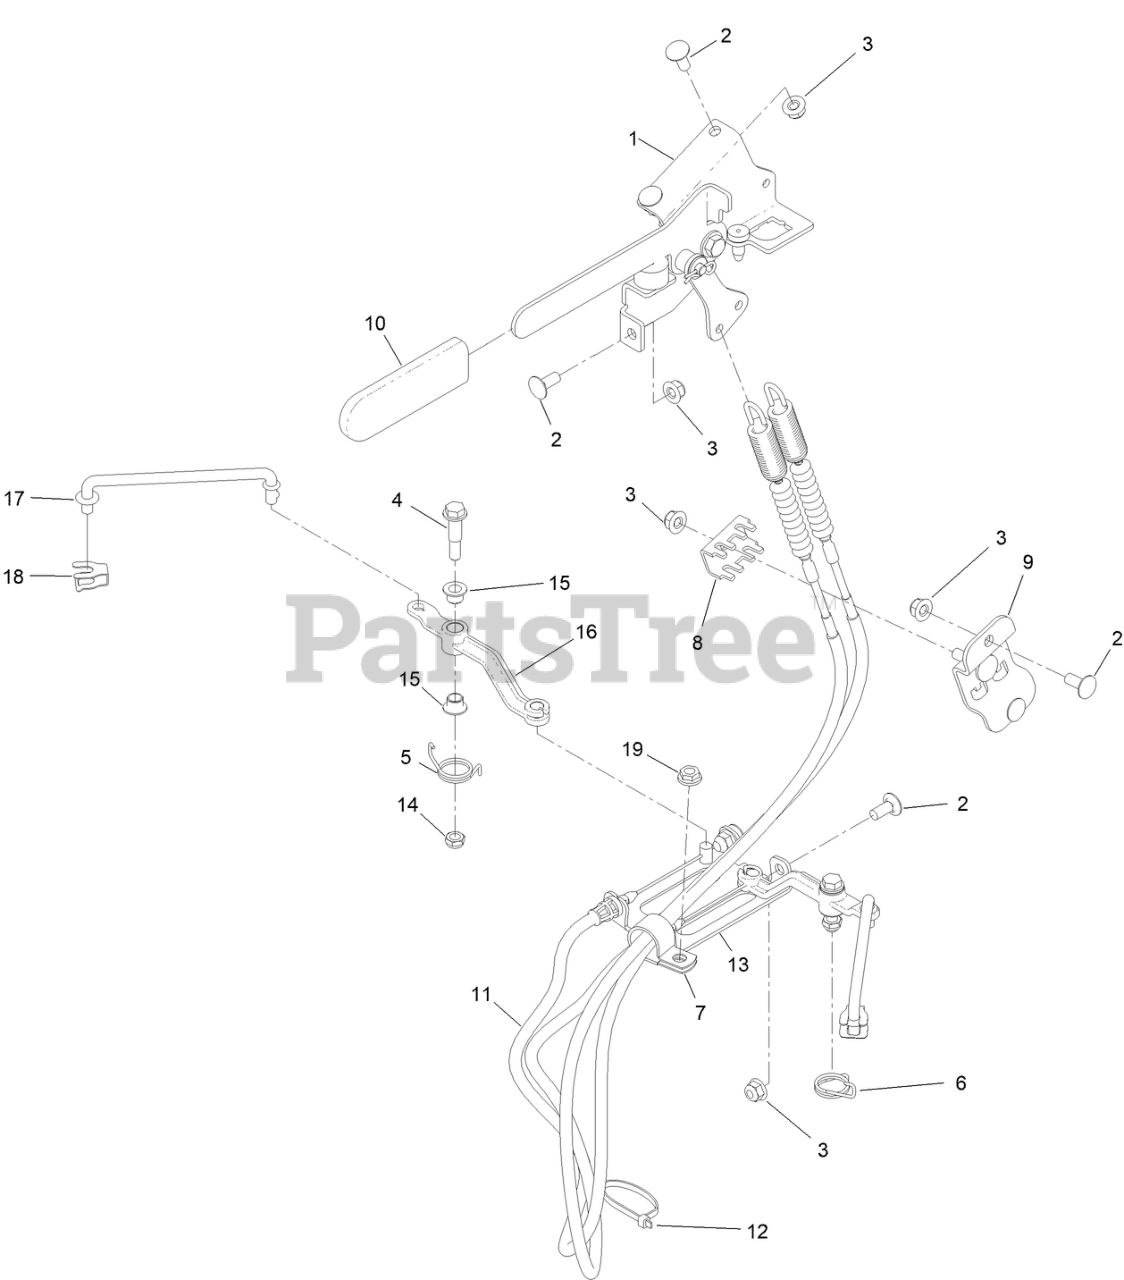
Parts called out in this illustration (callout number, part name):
1	BRAKE HANDLE ASM
2	SCREW-CARR
3	NUT-HF, NI
4	SCREW-SHOULDER
5	SPRING-TORSION
6	SPRING-TORSION
7	CLAMP-R
8	CLAMP-CABLE
9	MOUNT-CABLE, BRAKE
10	GRIP-LEVER
11	CABLE-BRAKE
12	TIE-CABLE
13	BRACKET-CABLE, MOUNT
14	NUT-LOCK, NI
15	BUSHING-FLANGE
16	ARM-BRAKE
17	ROD-BRAKE
18	RETAINER-ROD
19	NUT-HF
